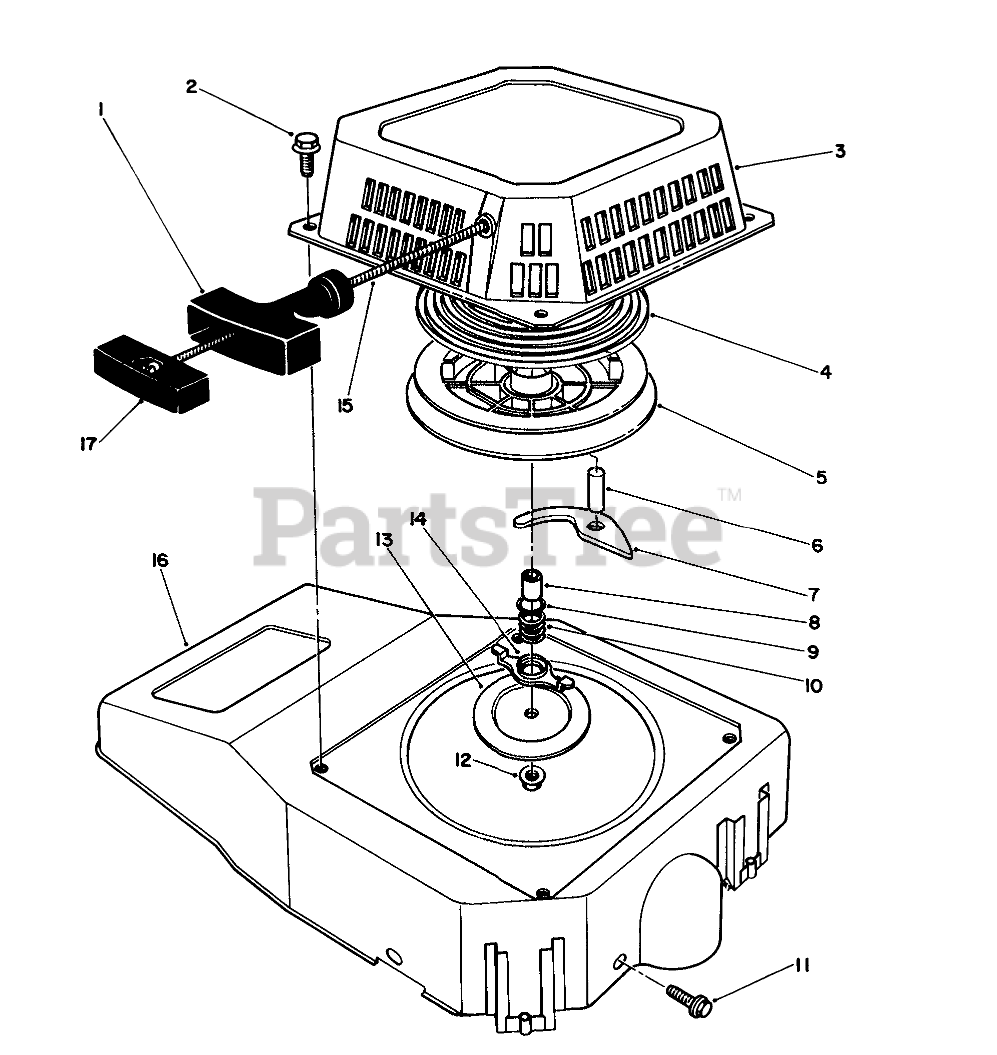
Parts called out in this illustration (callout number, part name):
1	HANDLE
2	SCREW-HHF
3	Case-Recoil
4	SPRING
8	Spacer
9	WASHER
10	Spring-Friction
13	PLATE
14	Guide-Paw
15	ROPE-STARTER
16	SHROUD
17	RETAINER HANDLE
